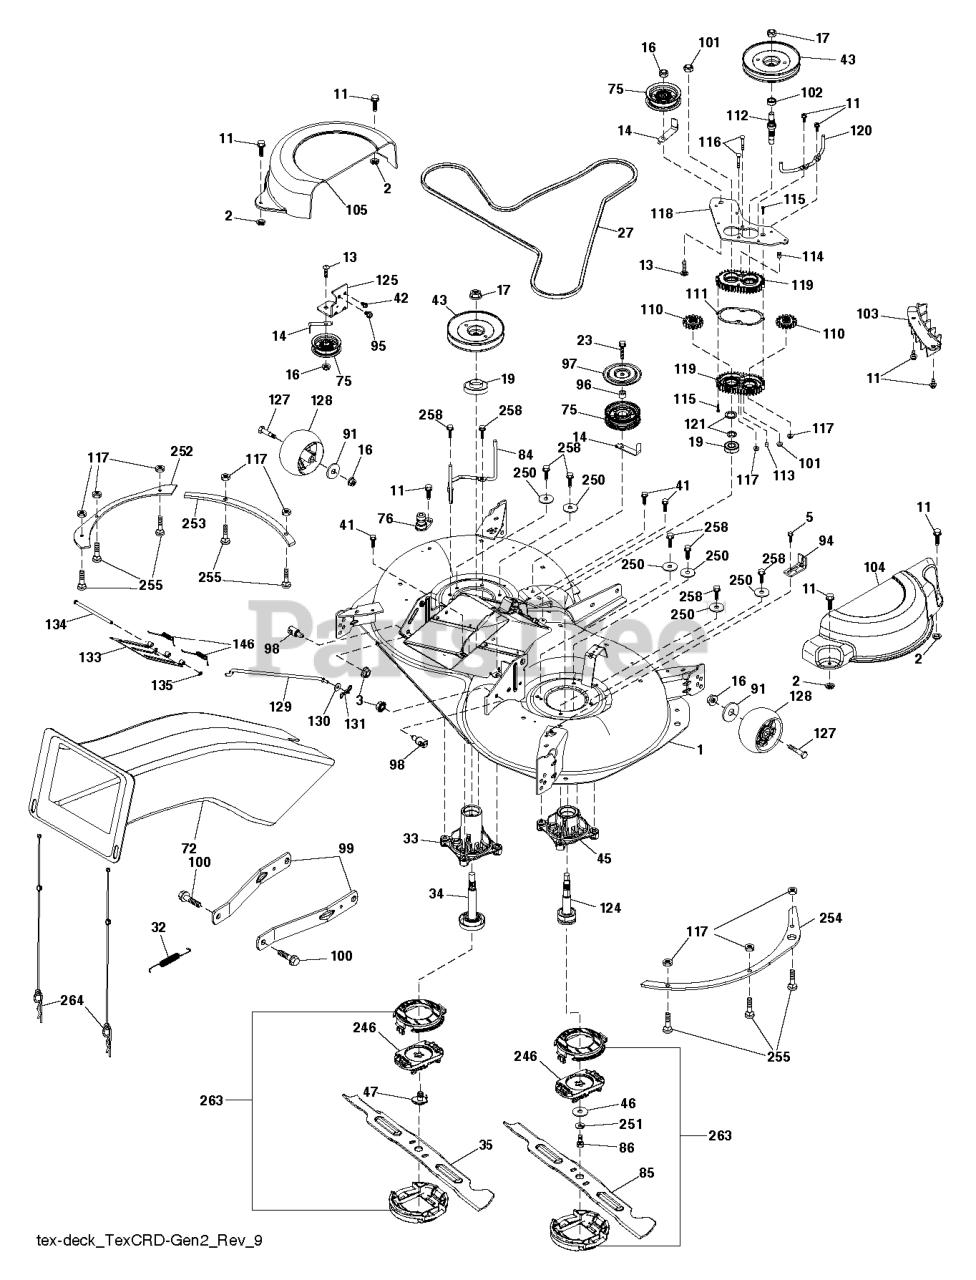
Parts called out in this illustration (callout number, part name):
1	DECK.SVC.WLDT.97EL.TCRD.EZ.498
2	PALNUT 1/4
3	NUT LOCK HEX FLANGE 5/16-18
5	BOLT.5/16HEX.WHS.HD
11	SCREW.1/4-20X5/8
13	BOLT.3/8-16X1.50
14	KEEPER, BELT IDLER
16	NUT LOCK FLG 3/8-16 UNC
17	NUT.FLANGE.LOCK.TOP
19	BEARING.MANDREL.TOP.EXTENDED
23	SCREW LT
27	BELT 97CM ELECTRIC
32	SPRING 107CM & 97CM ELECTRIC D
33	RP.HOUSG.MAND.REV.TALL.N/GRS
34	RP.SAFT ASM.REV.TALL.N/GREASE
35	BLADE.REVOLUTION.97CM.LHS
41	BOLT.HEX.WASHR.HED.313-18X1.19
42	SCREW
43	PULLEY.MANDREL.5.0.PD.38"
45	RP HOUSING.MANDREL.REV.REVS.
46	3/8 FLAT WASHER
47	SCREW.SEMS.7/16-20X1.HEX.HEAD
72	RP.CHUTE 107/97 TEX GENII
75	FLAT IDLER PULLEY
76	PORT.WASHOUT
84	BELT KEEPER.MANDREL.38"COATED
85	BLADE.REVOLUTION.97CM.RHS
86	BOLT.3/8-24X1.25GR8. LHTHRD
91	WASHER
94	BRKT.CLUTCH.CABLE
95	SCREW, 3/8-16X3/4
96	SPACER
97	PROTECTOR
98	STUD.FASTNER.W/ANTI-ROTATE
99	ARM.SUSPENSION.MOWER.R
100	BOLT.SHOULDER
101	NUT.CROWNLOCK.9/16 -18.UNC
102	SPACER BEARING
103	GUARD GUARD FRONT VENT
104	97.CRD.RH.MANDREL.COVER
105	MANDREL MANDREL COVER LH
110	CRD.SPUR.GEAR
111	GASKET GASKET GEARCASE
112	SHAFT SHAFT. CRD GEARCASE ADAP
113	PLUG PLUG OIL
114	VENT.BREATHER.1/8 NPT
115	SCREW
116	BOLT.CARIGE.SS.1/4-20X1.75GR5
117	NUT T
118	ARM ARM CLUTCHING
119	GEARCASE GEARCASE SUBASM
120	BRACKET KEEPER BELT RH
121	WASHER WASHER
124	SUB.ASM.REVERSE.THREAD.REV
125	BRACKET
127	BOLT.SHOULDER.3/8-16X3-5/8.
128	RP WHEEL. GUAGE RALLY
129	ROD ROD. SWAY CRD GEN II
130	WASHER
131	PIN.COTTER.5/16.BOW TI
133	DOOR
134	PIN PIN.HINGE
135	E-RING.5/16"
146	SPRING SPRING: EZ MULCH DOOR
246	HOLDER.BLADE.REVOLUTION
251	LOCKWASHER
252	PLATE.REINFORCEMENT.X431
253	PLATE.REINFORCEMENT.LHS.X431
254	PLATE.REINFORCEMENT.LHS.X431
255	RHSNB, 1/4-20 X 1, GR5
258	BOLT.HEX.WASHR.HED.313-18X1.19
263	CAP.REVOLUTION ASM
264	RETAINER.ASM.UPPERCHUTE.CRD2.5
